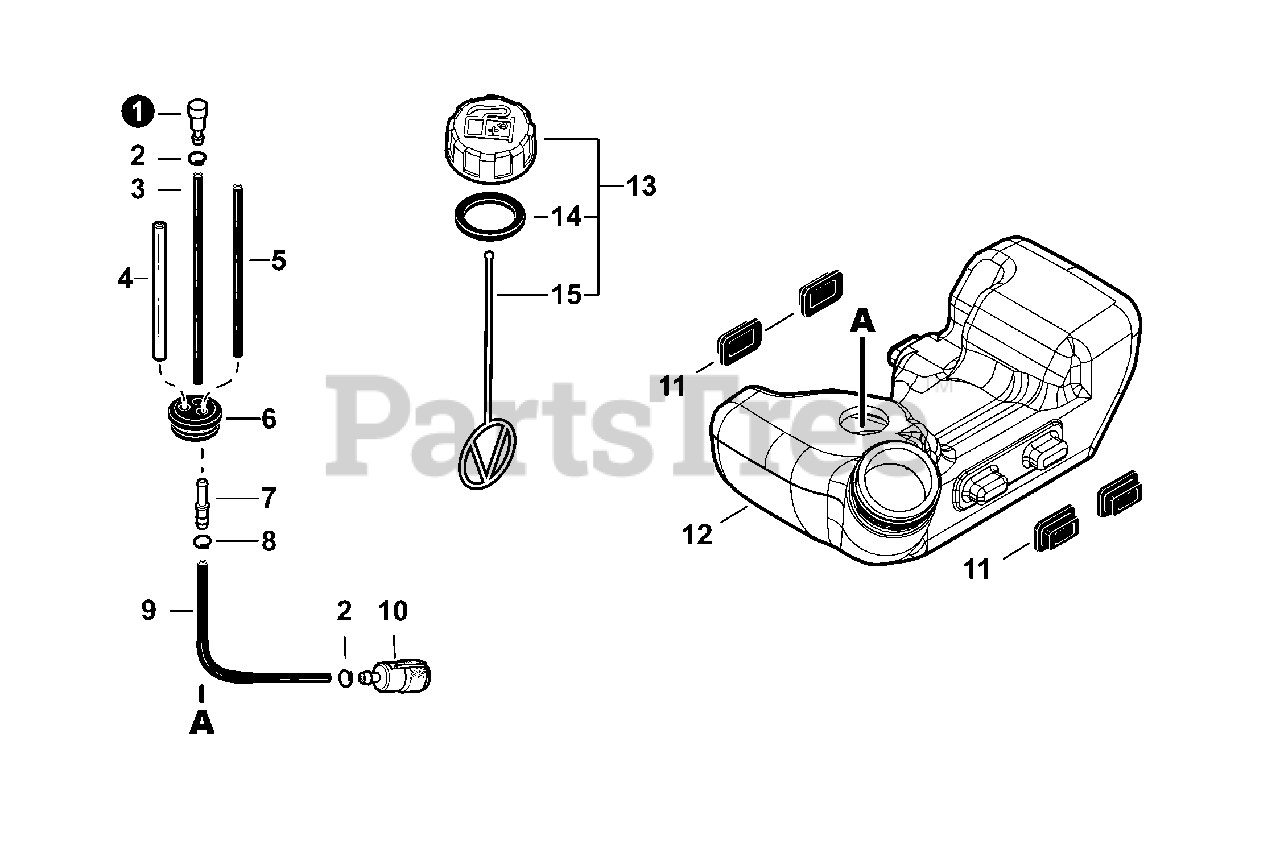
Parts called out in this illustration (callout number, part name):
1	VENT ASSY
3	PIPE 3×6×90mm
4	PIPE, FUEL 3×6×80 CLEAR
5	PIPE, FUEL 3×5×61
6	GROMMET, FUEL
7	CONNECTOR, PIPE 5×3.5
8	CLIP 6.5MM
9	PIPE, FUEL 3×6×120 BLACK
10	FILTER, FUEL
11	CUSHION, FUEL TANK
12	TANK, FUEL
13	CAP ASSY, FUEL
14	GASKET, FUEL CAP
15	CONNECTOR, CAP L= 123
